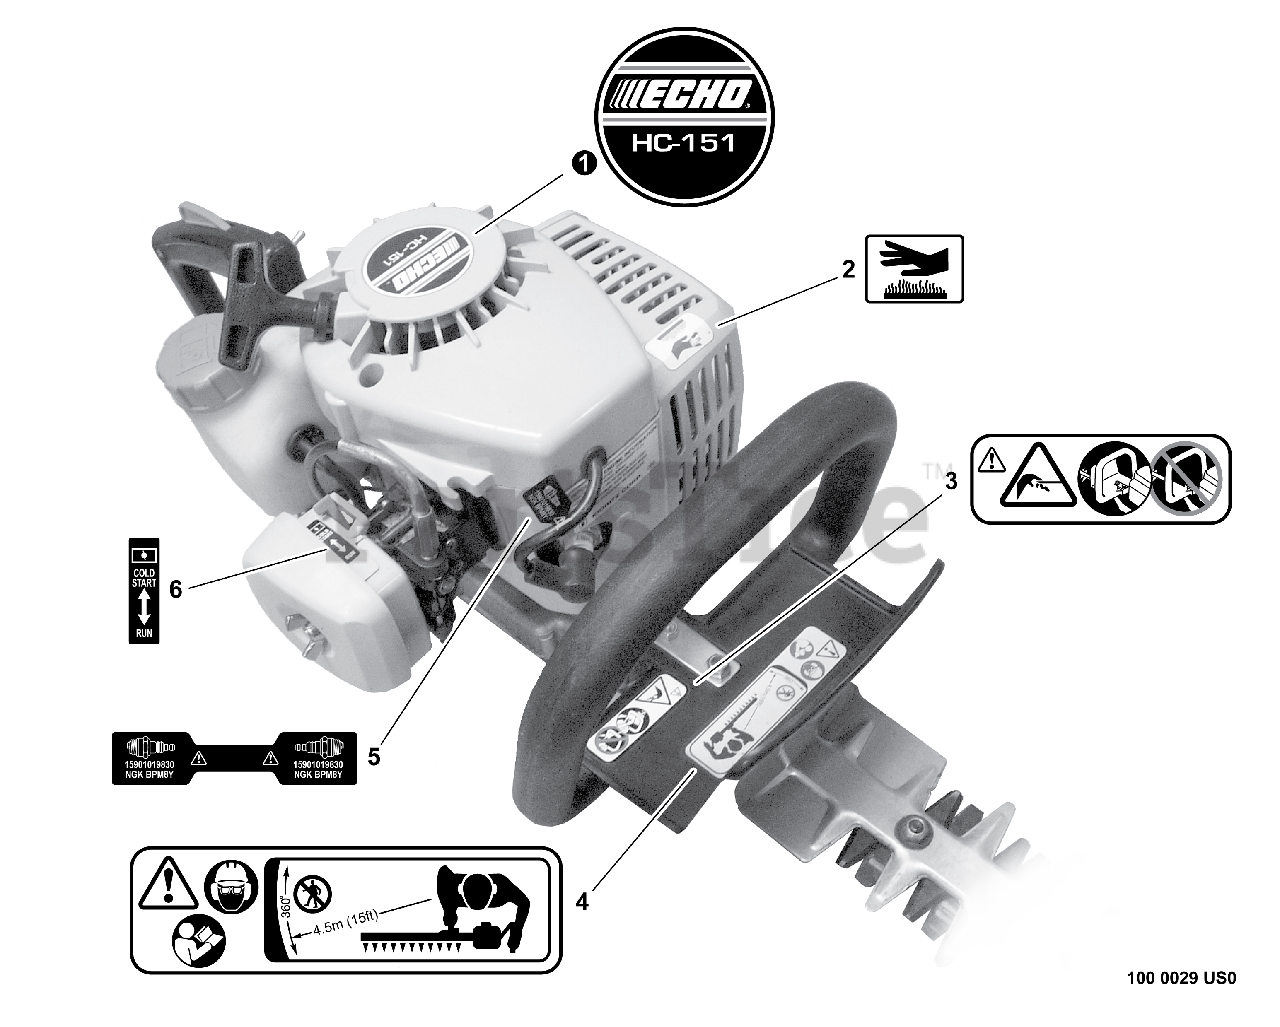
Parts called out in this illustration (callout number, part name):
1	LABEL - MODEL HC-151
2	LABEL - HOT SURFACE
3	LABEL - CAUTION
4	LABEL - CAUTION
5	LABEL - SPARK PLUG -- BPM-8Y
6	LABEL - CHOKE
